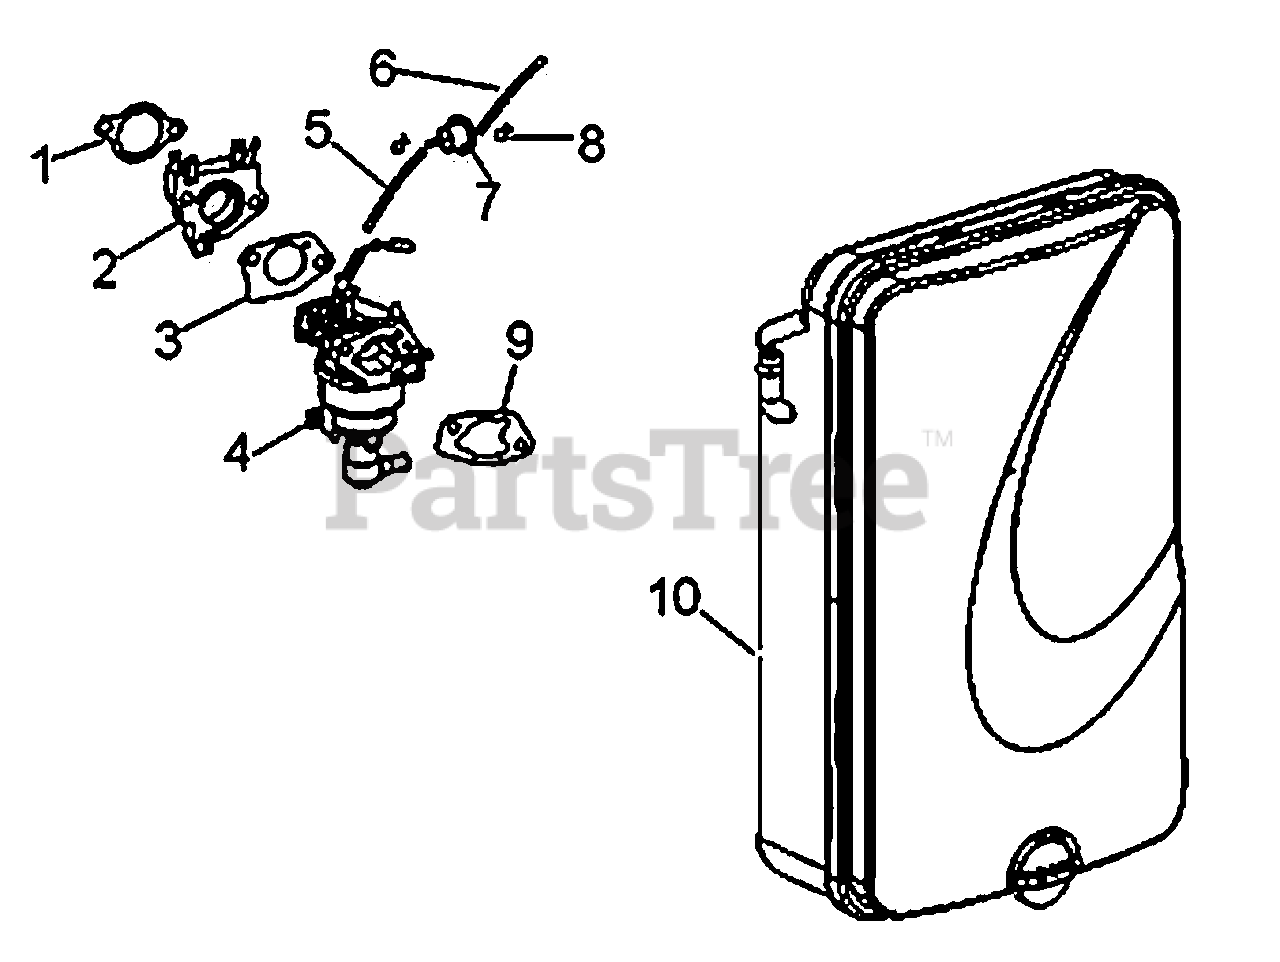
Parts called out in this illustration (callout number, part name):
1	GASKET, CARBURETOR
2	SPACER, CARBURETOR
3	GASKET, CARBURETOR
4	CARBURETOR ASSY.
5	HOSE, FUEL
6	HOSE, FUEL
7	FILTER, FUEL
9	GASKET, CARBURETOR
10	AIR CLEANER
